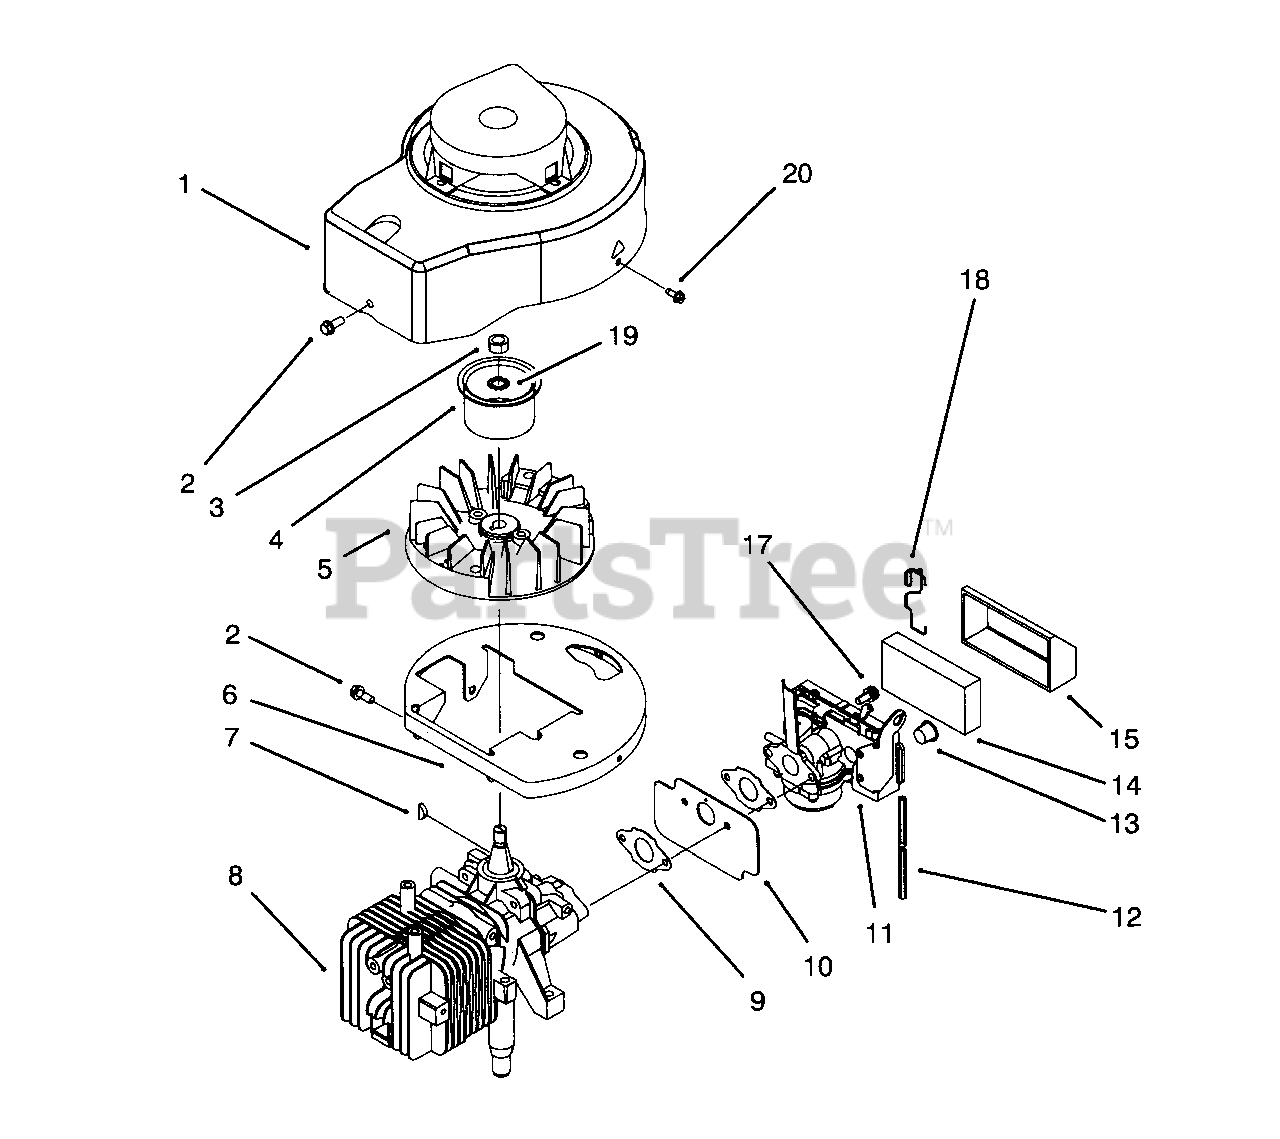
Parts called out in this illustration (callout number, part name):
1	Shroud Assembly
2	Screw
4	Hub-Starter
5	Flywheel Assembly
6	Base-Shroud
8	Short Block Assembly
9	Gasket-Carburetor
10	Shield-Carburetor
11	Carburetor Assembly
12	Hose-Primer
13	Plug
14	Element-Air Filter
15	Cover-Air Filter
18	Retainer-Filter
19	Washer-Lock
